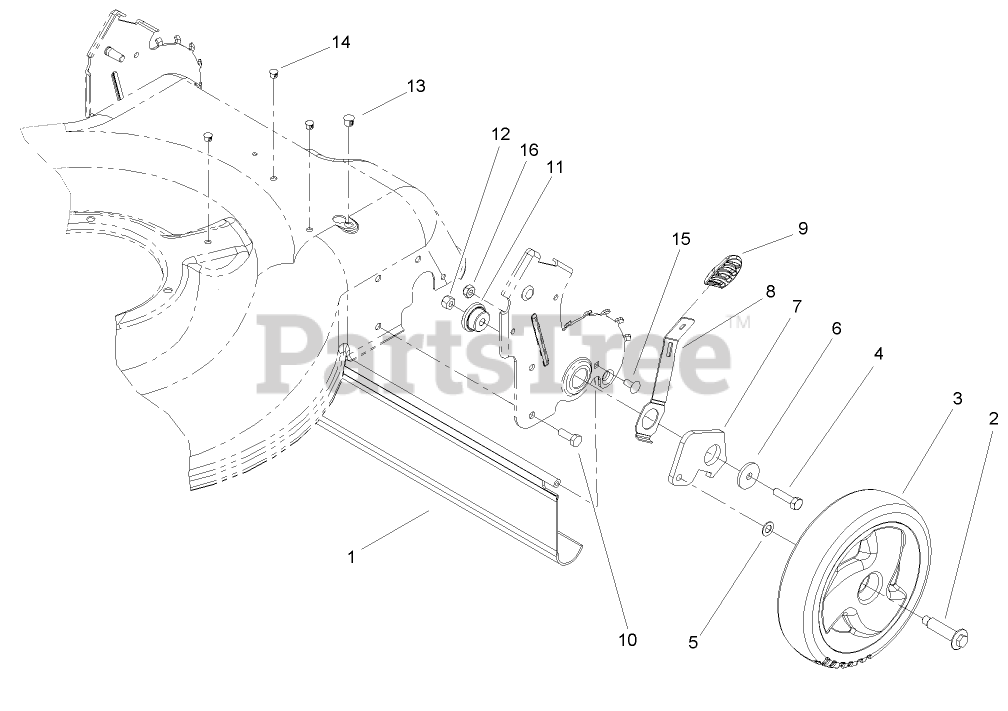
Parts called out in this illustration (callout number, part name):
2	BOLT-SHOULDER
3	WHEEL ASM (59505)
4	SCREW-HH
5	WASHER
6	WASHER-FLAT
7	ARM-PIVOT, REAR (LH)
8	ARM-SPRING
9	KNOB-LEVER, HOC
10	SCREW-HH
11	BUSHING-MOUNT, HOC
12	NUT-LOCK, NI
13	PLUG-DOME
14	PLUG-DOME
15	SCREW-CARR
16	NUT-LOCK, NI
